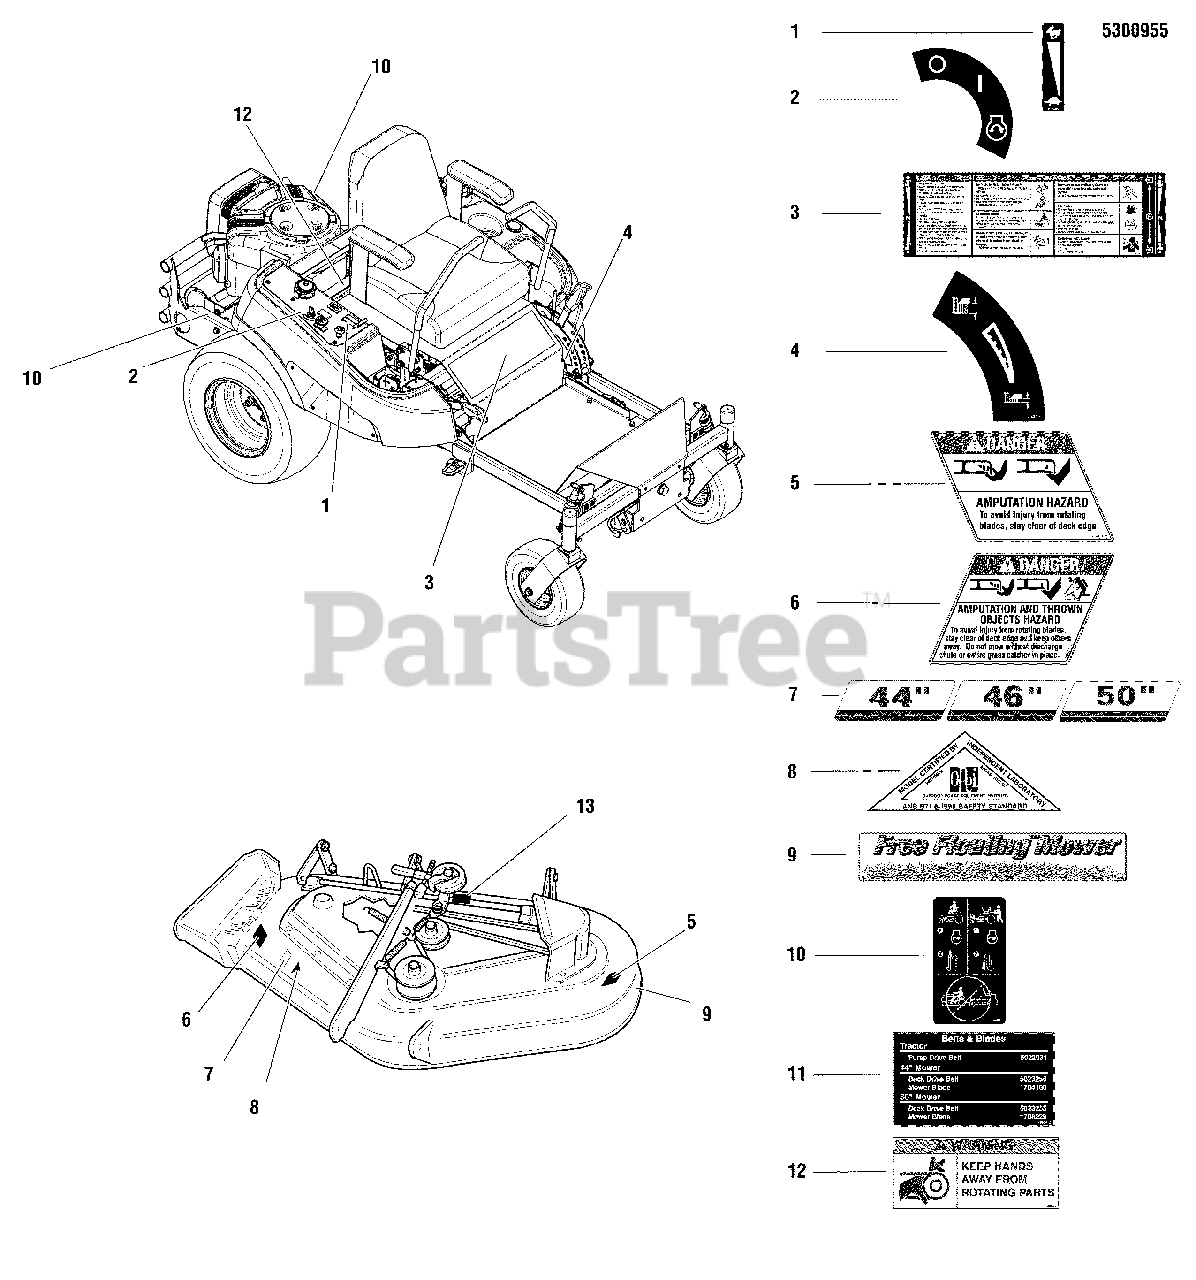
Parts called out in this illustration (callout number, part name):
1	DECAL, THROTTLE CONTROL
2	DECAL, IGNITION SWITCH
3	DECAL, MAIN
4	DECAL, HEIGHT OF CUT
5	DECAL, DANGER, MOWER
6	DECAL, DANGER, MOWER DISCHARGE
7	DECAL-44"- SILVER ON BLACK W/STRIPE
7	DECAL, 50"-SILVER ON BLACK W/STRIPE
7	DECAL-46"-SILVER ON BLACK W/STRIPE
8	DECAL-OPEI CERTIFIED ANSI B71.12003 GOLD
9	DECAL-FREE FLOATING MOWER- SILVER
10	DECAL, TRANSAXLE RELEASE
11	DECAL, BELT & BLADE, CONS Z
12	DECAL, WARNING
13	TAG, PRINTED SERIAL
14	DECAL, HYDRAULIC OIL, SAE 20W-50
